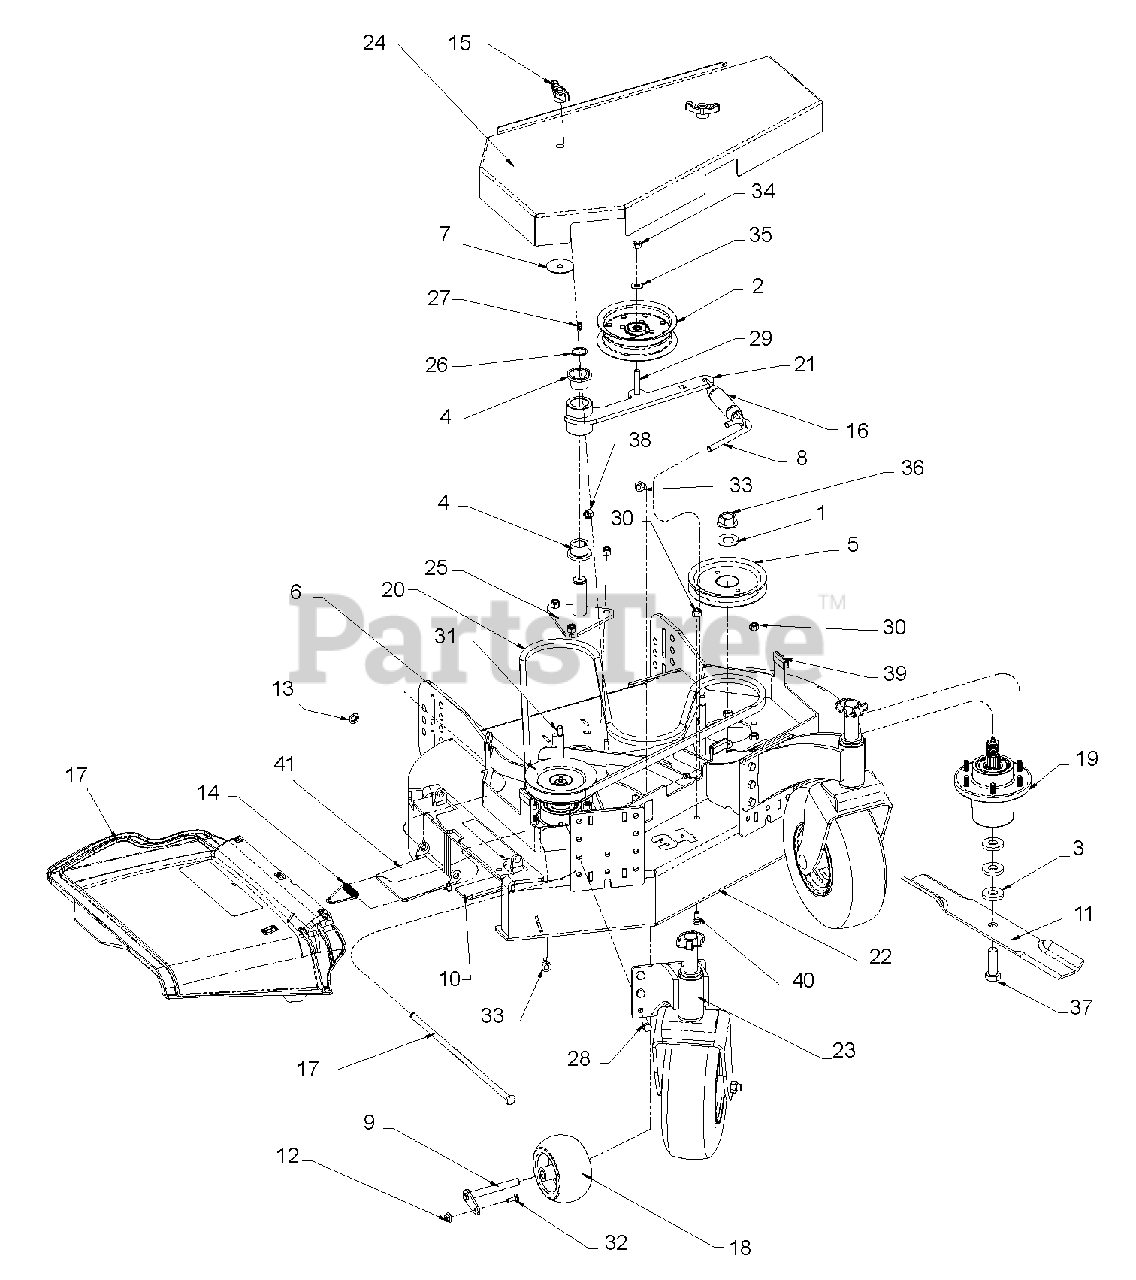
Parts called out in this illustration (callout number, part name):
1	Washer, .75 x 1.3125 x .120
2	Pulley, Flat 5.0 x .38 w/Bearing
3	Washer, Blade
4	Bearing, Flg 1.00 x 1.25 x 1.00
5	Pulley, Spline Spindle Offset
6	Pulley, V-belt 5.27 x .990 w/Spl
7	Washer, .402 x 2.00 x .055 Fend Y
8	J-bolt, 3/8-16 x 4.00 Y
9	Pivot, Retainer Weld
10	Blade, 16.50 Lo-Lift
11	Blade, 18"
12	Nut-1/4" Flange
13	Retainer
14	Spring, Chute Guard
15	Knob, Locking
16	Spring, Tension
17	Discharge Chute, 48" Deck
18	Wheel, Gage
19	Assembly, Spindle Housing
20	Belt, HB 80.3 El AMD OHR
21	Weldment, Idler Arm
22	Weldment, 34" Deck w/Decals
23	Assembly, Front Wheel Caster (see page 16 for parts)
24	Shield, Deck 34 w/Decals
25	Weldment, Idler Pivot
26	Snap Ring, 1.00 x .042 Ext
27	Grease Zerk, 1/4-28 Straight .69 LG
28	Bolt, Hex .38-16x1.0
29	Bolt, 3/8-16 x 2.25 Hex 5 Y
30	Nut, Hex .38-16 Grade 5 Y
31	Bolt, .38-16 x 1 Grade 5 Round Head Square Neck
32	Bolt, 1/4-20 x .750 Round Head Square Neck 5 Y
33	Nut, Flange .375-16
34	Nut, .38-16 Low Crown Locking Acorn
35	Washer, .406 x .813 x .065 Flat Y
36	Nut, 3/4-16 Flange Grade 8 Y
37	Bolt, 5/8-11 x 2.00 Hex 8 Y
38	Nut, Locking-Nylon .38-16
39	Trim 1/4
40	Bolt, 5/16-18 x .750 Hex 5 Y
41	Bracket, Chute Support
